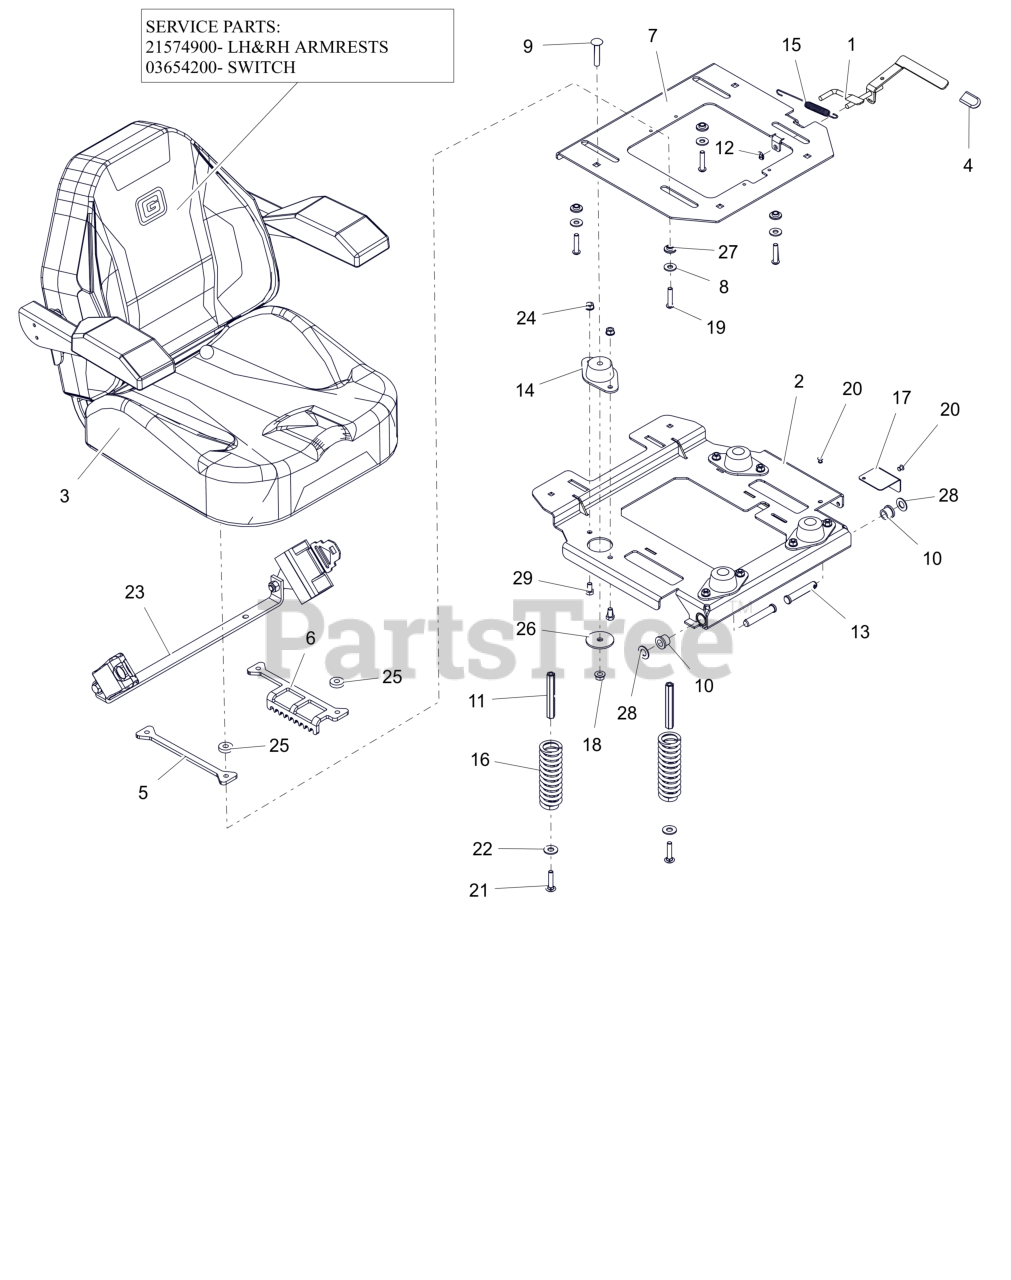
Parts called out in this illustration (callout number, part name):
1	WLDMT, SEAT SLIDE LEVER
2	WLDMT, ISO MTG PLATE (BLACK)
3	SEAT, HD
3	LH&RH ARMRESTS
3	SWITCH
4	GRIP, SEAT LEVER, GREY
5	PLATE, ADJ SEAT SLIDE (BLACK)
6	PLATE, SEAT ADJ (BLACK)
7	PLATE, SEAT MOUNTING (ISO KIT) (RED)
8	WSHR,FLT .375X.875X.083 ZCC
9	BLT,RHSSN.375-16X2.00 G5 ZCC
10	BSHG, FLG .516X.750X.625X.937
11	NUT, COUPLING 5/16X18 X 3.75
12	NUT-PUSH .312
13	PIN, SLIC-.500X42.70X2.31 -ZC
14	MOUNT, FAIL-SAFE COMPRESSION
15	SG-TENS .06X.482X5.35
16	SPRING, COMPRESSION SEAT 224LB
17	GUARD, SEAT FAN (SH)(BLACK)
18	NUT-LK-CTR-FLG .375-16 GF ZCC
19	SCR,BTNHD .31-18X1.50 ZCC
20	RIVET, .1875 AL/AL .126-.250
21	BLT,RHSN .31-18X1.50 G5 ZCC
22	WSHR,FLT .438X1.00X.083 ZCC
23	KIT-SEAT BELT REPLACE-05007300
24	NUT,LK-CTR-FLG .31-18 GF ZCC
25	WSHR, FLT .390X1.00X.250 ZCC
26	WSHR-FL-STL 0.406X2X0.125 ZCC
27	BSHG-FLG .325X.499X.3X.875
28	WSHR, FLT .531X1.00X.063 ZCC
29	BLT, HEX .31-18X.625 G5 ZCC
